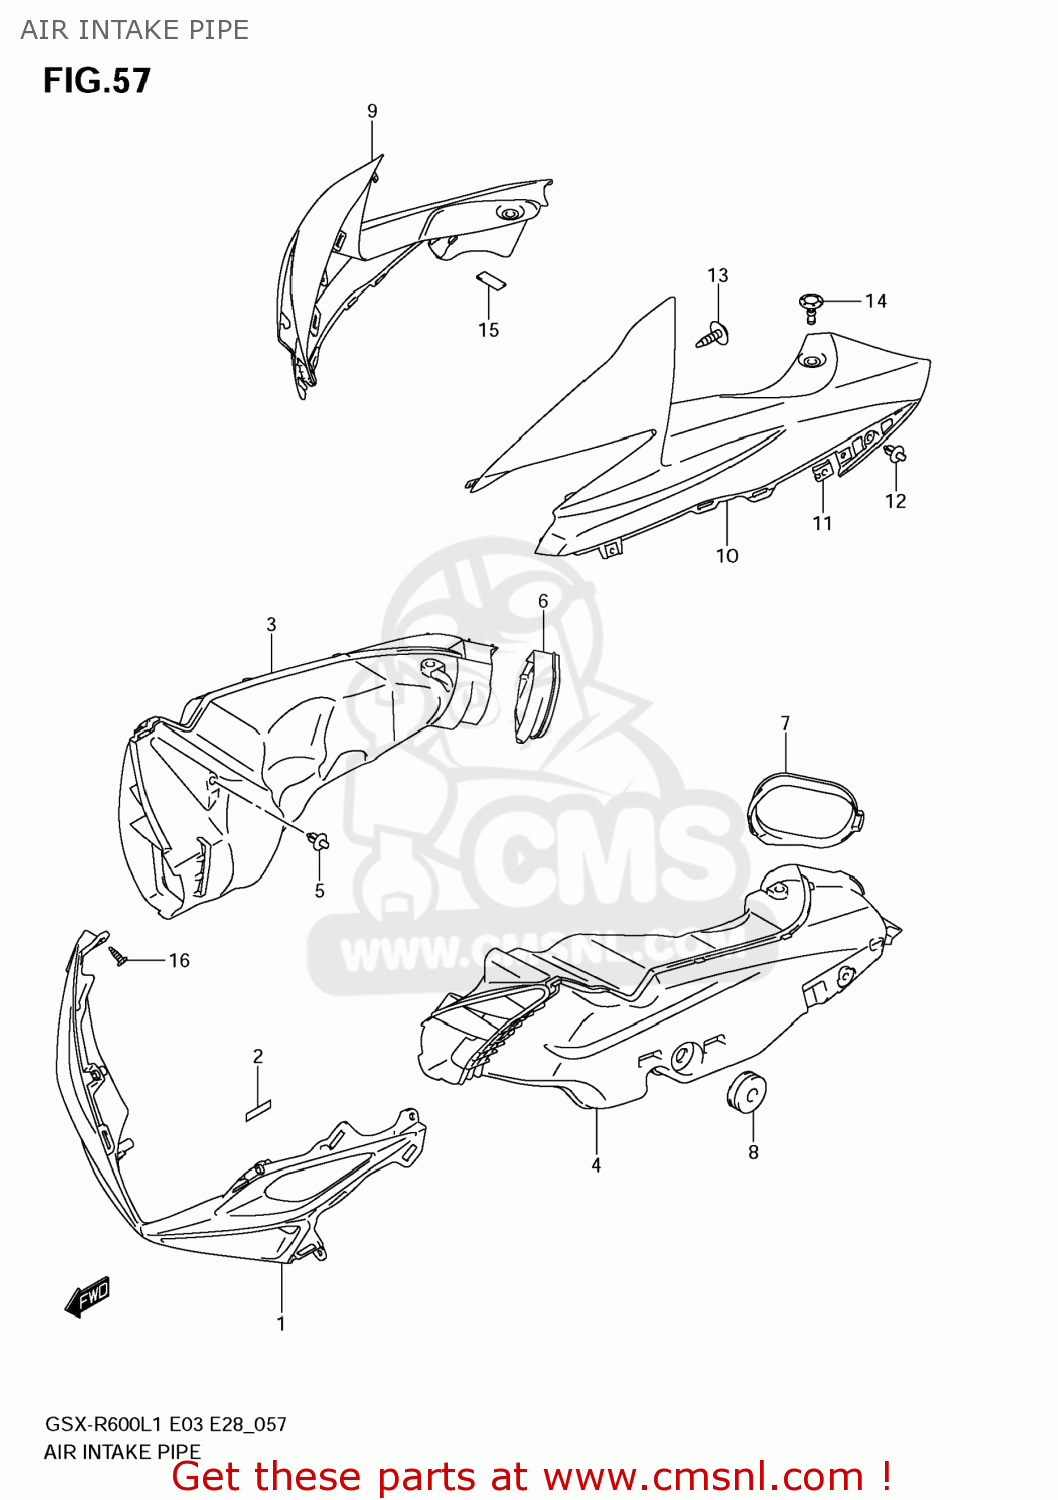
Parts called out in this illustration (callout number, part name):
1	COVER,INTAKE
2	TAPE(6X25X0.13)
3	PIPE,AIR INTAKE,R
4	PIPE,AIR INTAKE,L
5	CLIP(BLACK)
6	MOLDING,AIR INTAKE,R
7	MOLDING,AIR INTAKE,L
8	CUSHION
9	COVER,INTAKE,R
10	COVER,INTAKE,L
11	NUT
12	CLIP(BLACK)
13	SCREW(5X12)
14	CLIP
15	PROTECTOR(30X80X1)
16	SCREW
